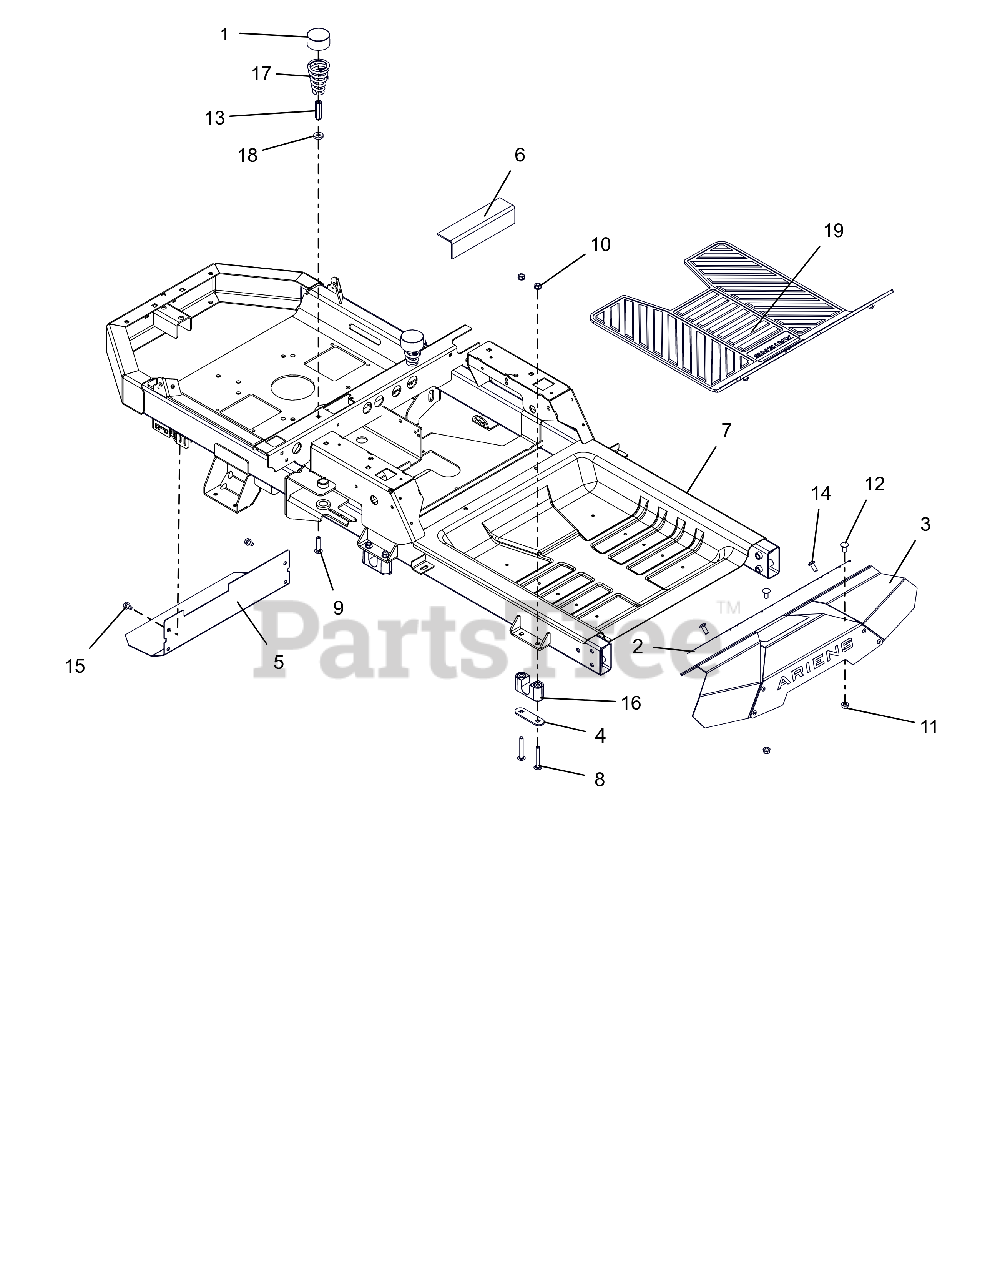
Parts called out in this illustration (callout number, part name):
1	HUB CAP
2	GRIP TAPE, FOOT PLATE
3	KIT, IKON FOOT REST W/DECAL
4	PLATE, BEARING SUPPORT
5	HEAT, SHIELD
6	PAD, RUBBER-TANK
7	KIT, IKON-X/XL FRAME (2016)
8	BLT-RDHDSQSHNK .31-18X2.25 YWZ
9	BLT,RHSN .31-18X1.50 G5 ZCC
10	NUT,LK-CTR-FLG .31-18 GF ZCC
11	NUT-LK-TOP-FLG .312-18 GF ZCC
12	BLT,RHSN .31-18X.75 G5 ZCC
13	NUT, COUPLING 5/16-18 X 1 3/4
14	SCR-RDHDSKTAP .31-18 X .75
15	SCR,TAP .312-18X.50 HWH TR ZCC
16	BSHG, DECK LIFT PIVOT
17	SPRING, SEAT
18	WSHR, FLT .328X.870X.179 ZCC
19	FLOOR MAT, RUBBER - ARIENS
